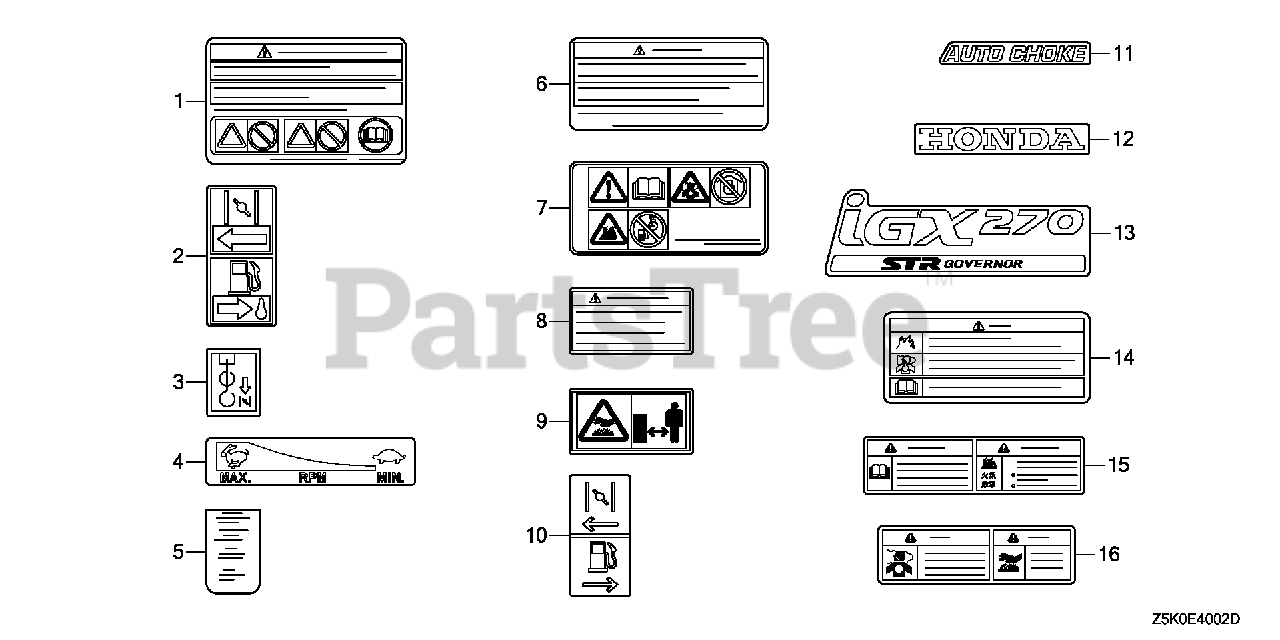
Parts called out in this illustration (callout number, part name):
6	MARK, OPERATOR CAUTION (FRENCH)(MADE IN THAI)
7	MARK, OPERATOR CAUTION (PICTOGRAPH)
8	MARK, EX. CAUTION (ENGLISH)
8	MARK, EX. CAUTION (FRENCH)
